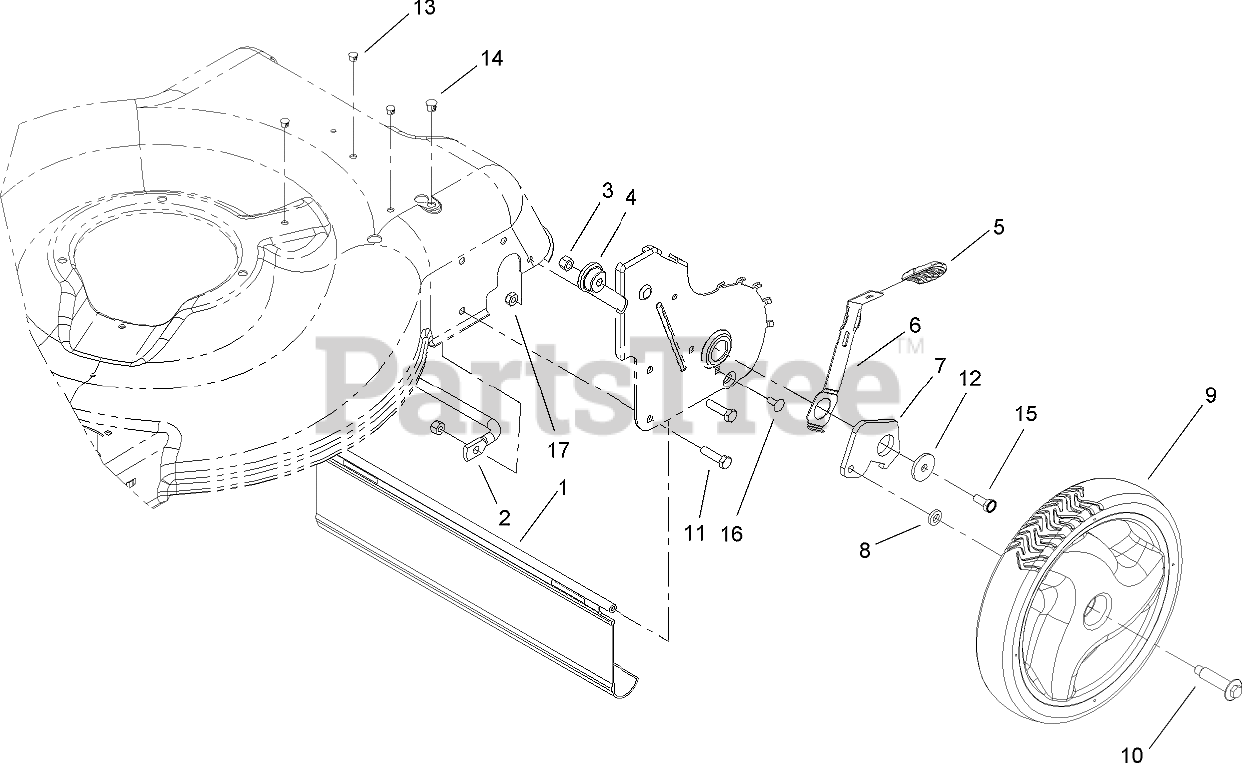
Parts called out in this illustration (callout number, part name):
1	SHIELD-TRAILING
2	BRACE-PLATE, HOC
3	NUT-HEX, SIDE DEFORM
4	BUSHING-MOUNT
5	Knob-Lever, HOC
6	ARM-11 INCH SPRING, REAR
7	Arm-Pivot, Rear (LH)
8	WASHER-BOLT, WHEEL
9	11 INCH WHEEL ASM
10	BOLT-SHOULDER
11	SCREW-HH
12	Washer-Flat
13	Plug-Dome
14	Plug-Dome
15	SCREW-HH
16	SCREW-CARR
17	NUT-LOCK, NI
